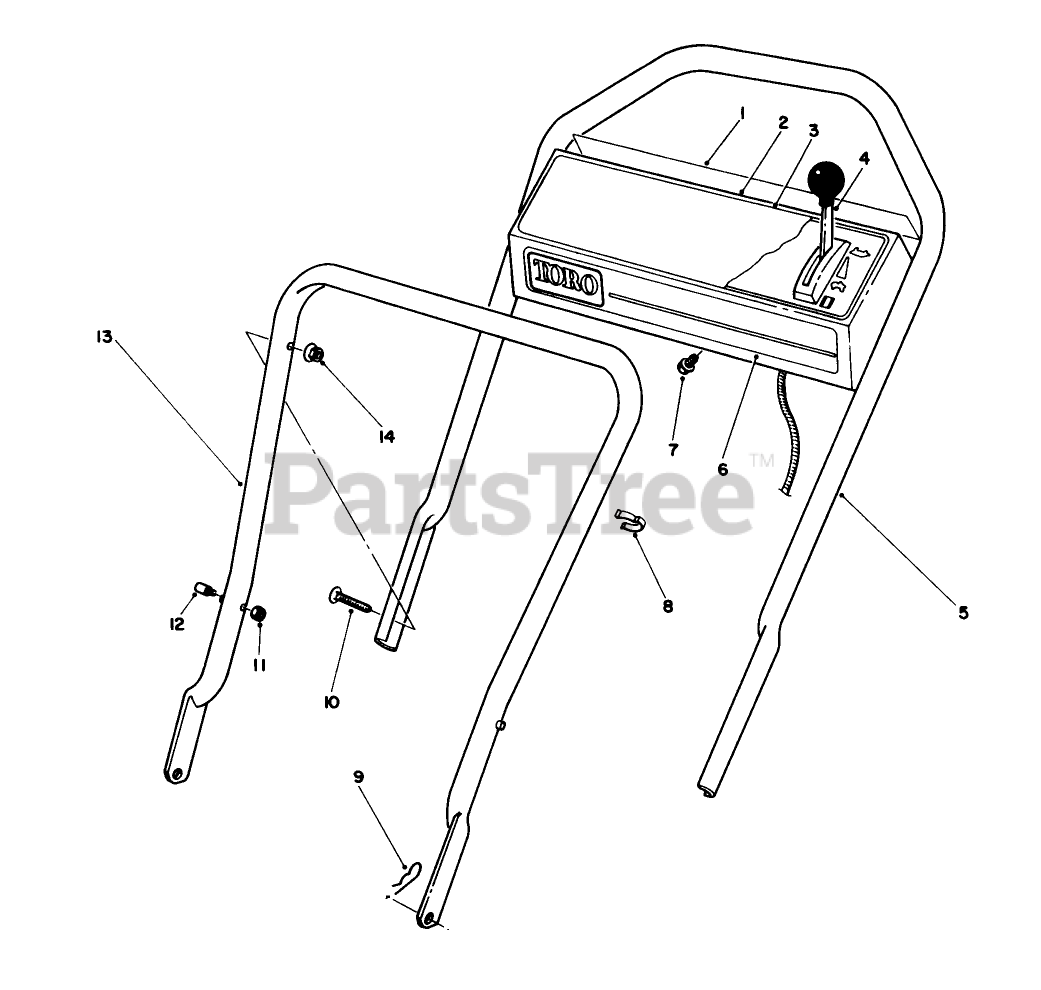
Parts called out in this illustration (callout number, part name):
4	THROTTLE CONT-SERVICE
7	SCREW-HWHTF
8	BOWDEN CLIP
9	PIN-COTTER, HAIR
11	Locknut
12	HANDLE PIN
13	LOWER HANDLE ASM
14	NUT-LOCK, NI
